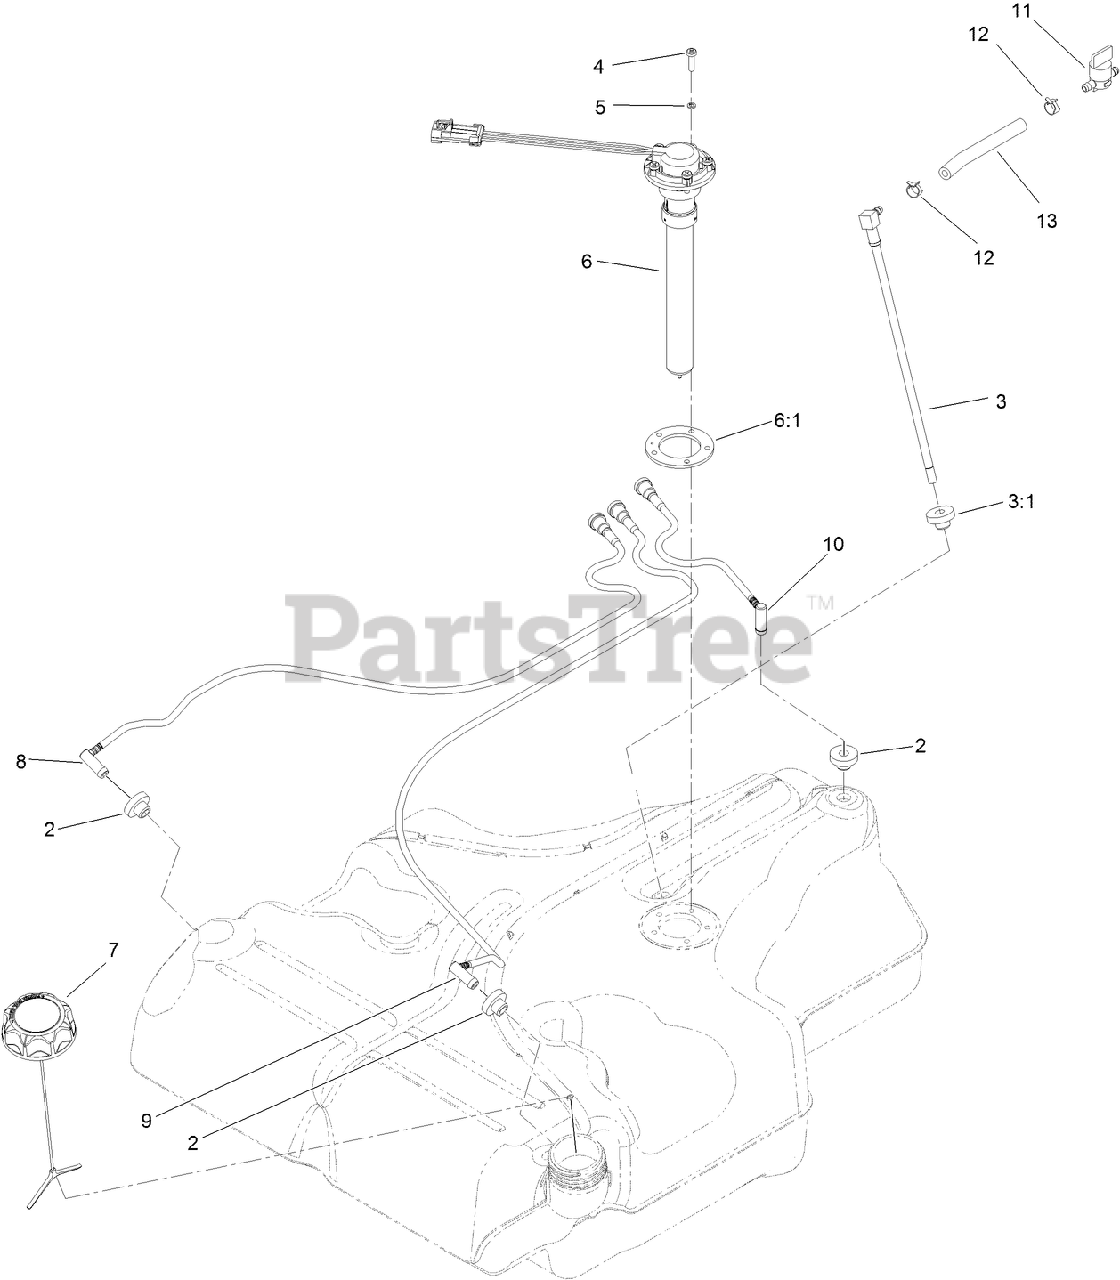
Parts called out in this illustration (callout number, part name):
2	BUSHING
3	FUEL LINE KIT (WITH GROMMET)
3:1	BUSHING
4	SCREW-PAN
5	WASHER-LOCK
6	SENDER-LEVEL, FUEL
6:1	GASKET-SENDER, FUEL
7	CAP-FUEL, RATCHETING
8	RH VENT LINE KIT (WITH GROMMET)
9	LH VENT LINE KIT (WITH GROMMET)
10	REAR VENT LINE KIT (WITH GROMMET)
11	VALVE-FUEL
12	CLAMP-HOSE
13	HOSE-FUEL
